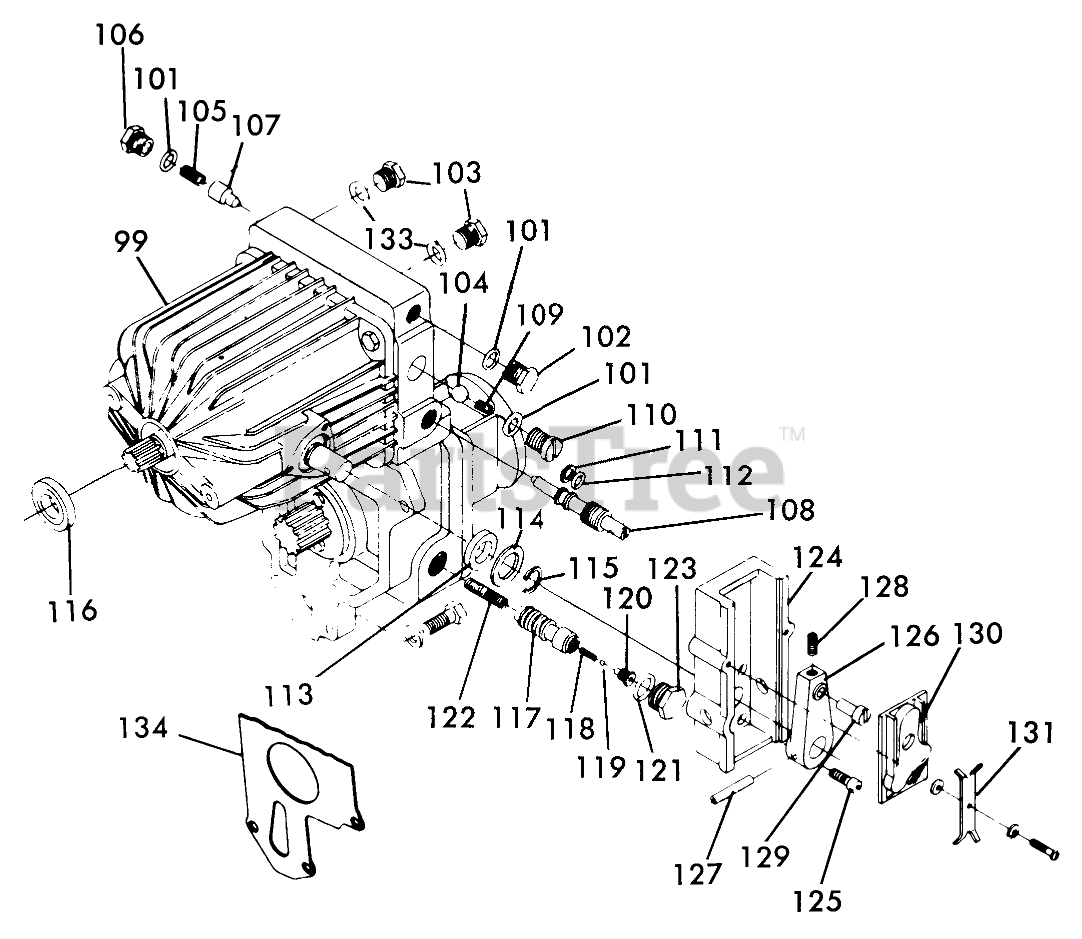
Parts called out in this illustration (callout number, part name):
99	SRV BULLT 437B
101	O RING
111	O-RING
130	CAM
134	GASKET
